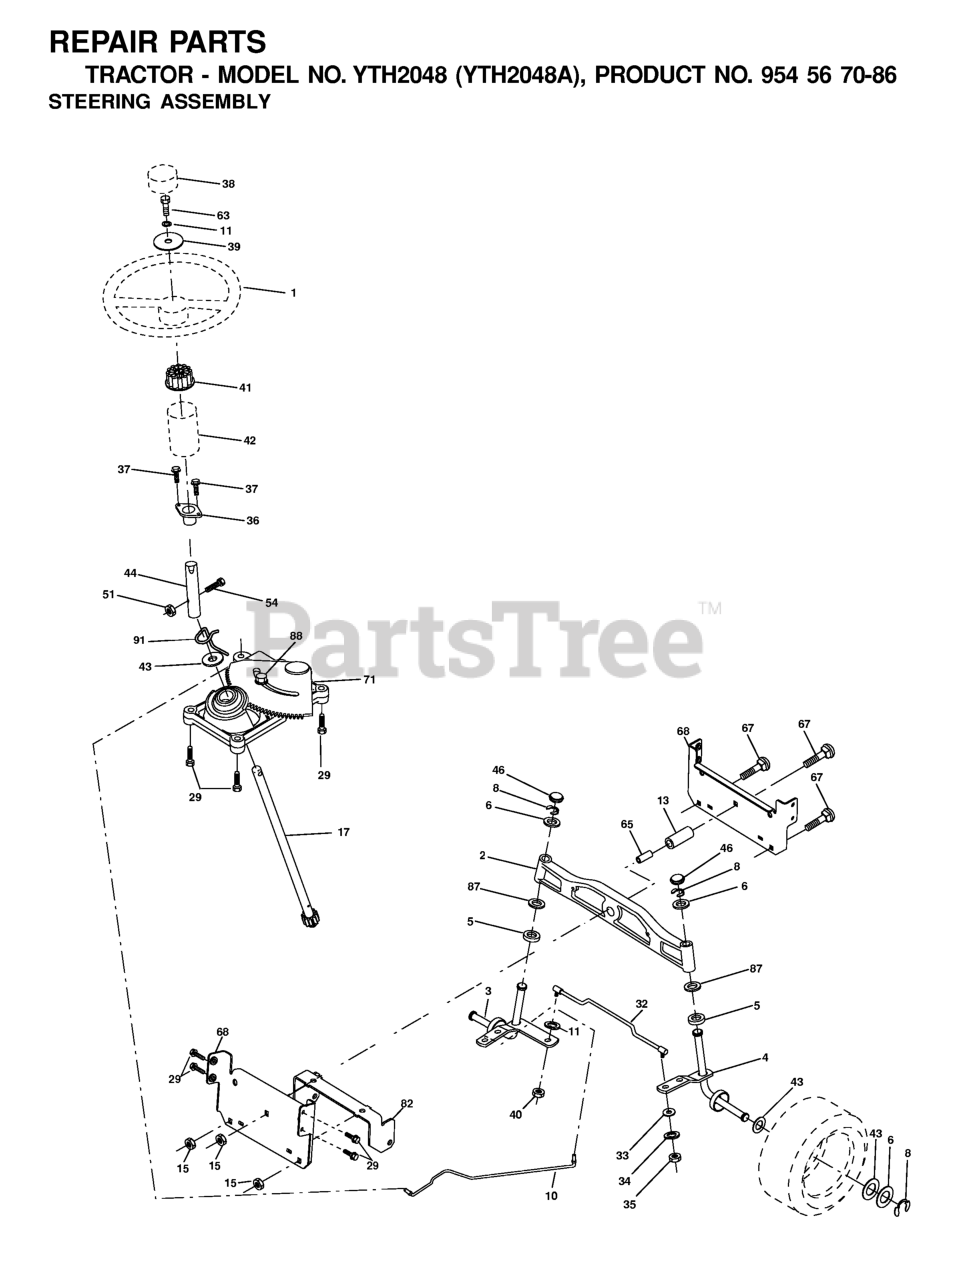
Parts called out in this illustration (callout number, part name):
1	STEERING WHEEL
2	AXLE ASM
3	SPINDLE.ASM.LH.15"TIRES
4	SPINDLE.ASM.RH.15"TIRES
5	THRUST WASHER
10	DRAGLINK.15".TIRES.2001
11	WASHER, LOCK 3/8
13	TUBE, PIVOT AXLE
15	NUT
17	SHAFT ASM
29	SCREW 3/8-16X3/4
32	ROD.ASM.TIE.BALL.JOINT.NOVAN
33	WASHER M
34	WASHER.LOCK.HVY.HLCL.SPR.5/16
35	NUT, CROWNLOCK
36	BUSHING, STEERING
37	SCREW.TT.#10-32X.5.3/8.FLANGE
38	CAP.WHEEL.STEERING.GREY
39	Washer 13/32 x 1-1/20 x 11 Gauge
40	GRIPCO NUT
41	STEERING WHEEL ADAPTOR
42	BOOT STEERING
44	EXT SHAFT STEERING
46	CAP.SPINDLE.BLACK
51	NUT.71038.31-18.HEX.NYLOCK
54	BOLT.5/16-18X1-1/4 FULL.THREAD
65	SPACER BRACE AXLE
67	BOLT
68	BRACE.AXLE.15"TIRES
71	STEERING ASM
82	BRACKET
87	WASHER, FLAT .781 X 1 1/2"
88	BOLT, SHOULDER 7/16-20
91	CLIP.STEERING
